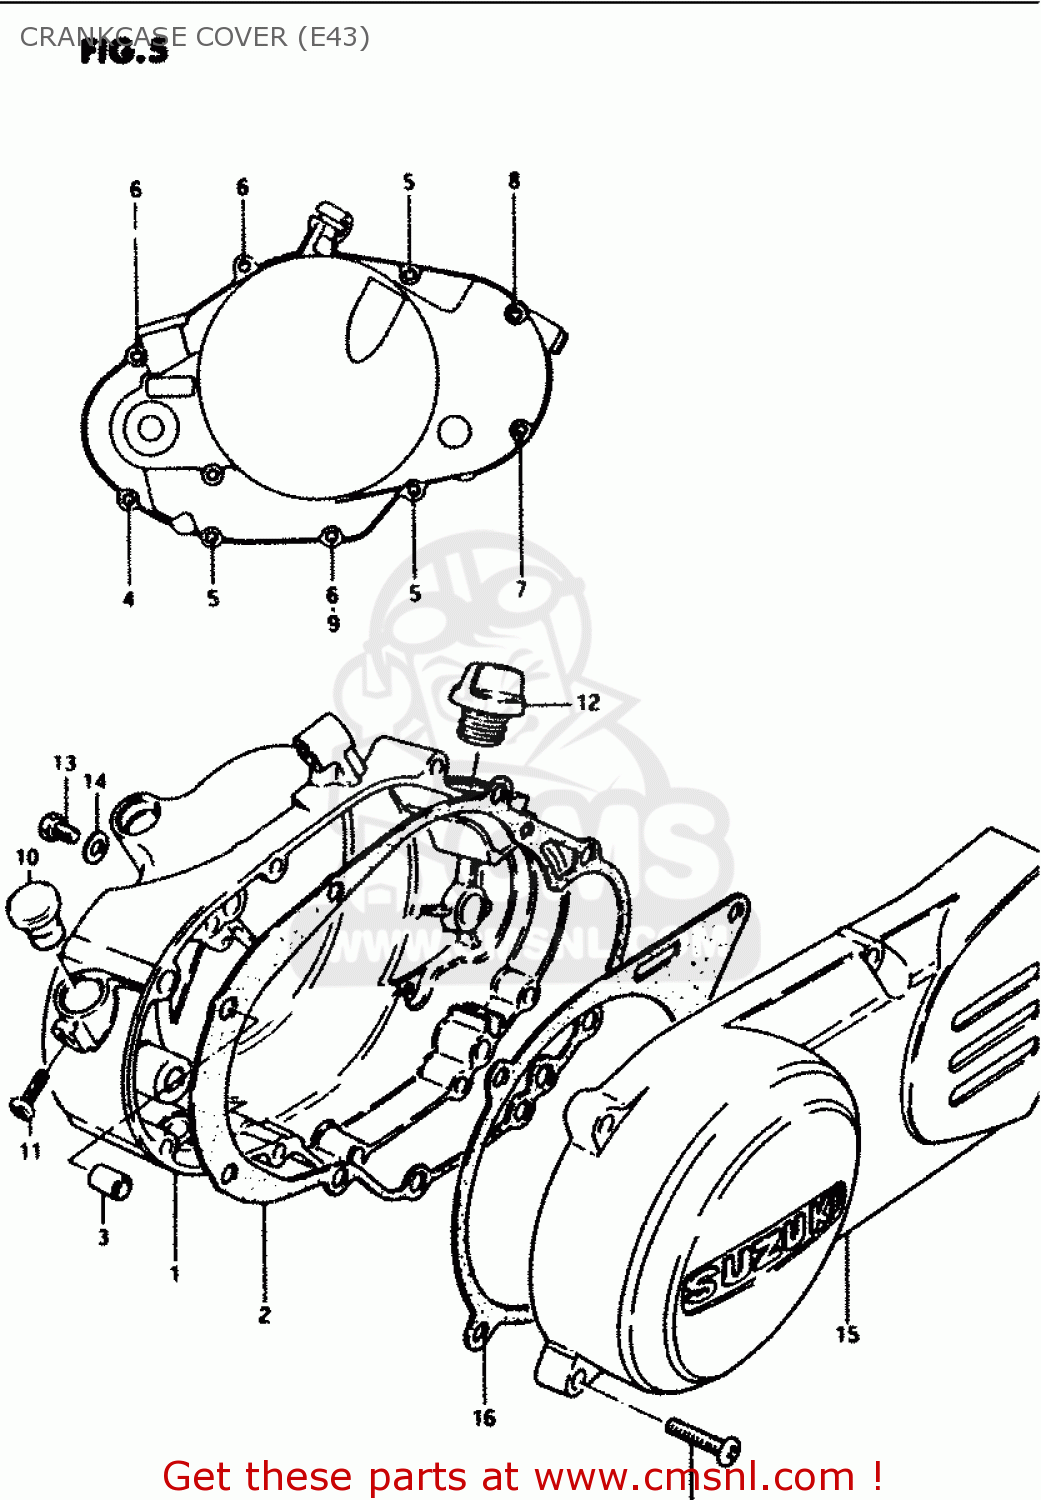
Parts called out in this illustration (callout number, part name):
1	COVER SET,CLUTCH
2	GASKET,CLUTCH COVER (NAS)
3	PIN
4	SCREW
5	SCREW 6X30
6	SCREW
7	SCREW
8	SCREW 6X60
9	GASKET(6.2X11X1).2 (NAS)
10	Plug
11	SCREW,6X6
12	PLUG
13	SCREW(6X10)
14	GASKET(6.2X11X1) (NAS)
15	COVER,MAGNETO
16	GASKET,MAGNETO COVER (NAS)
17	SCREW
